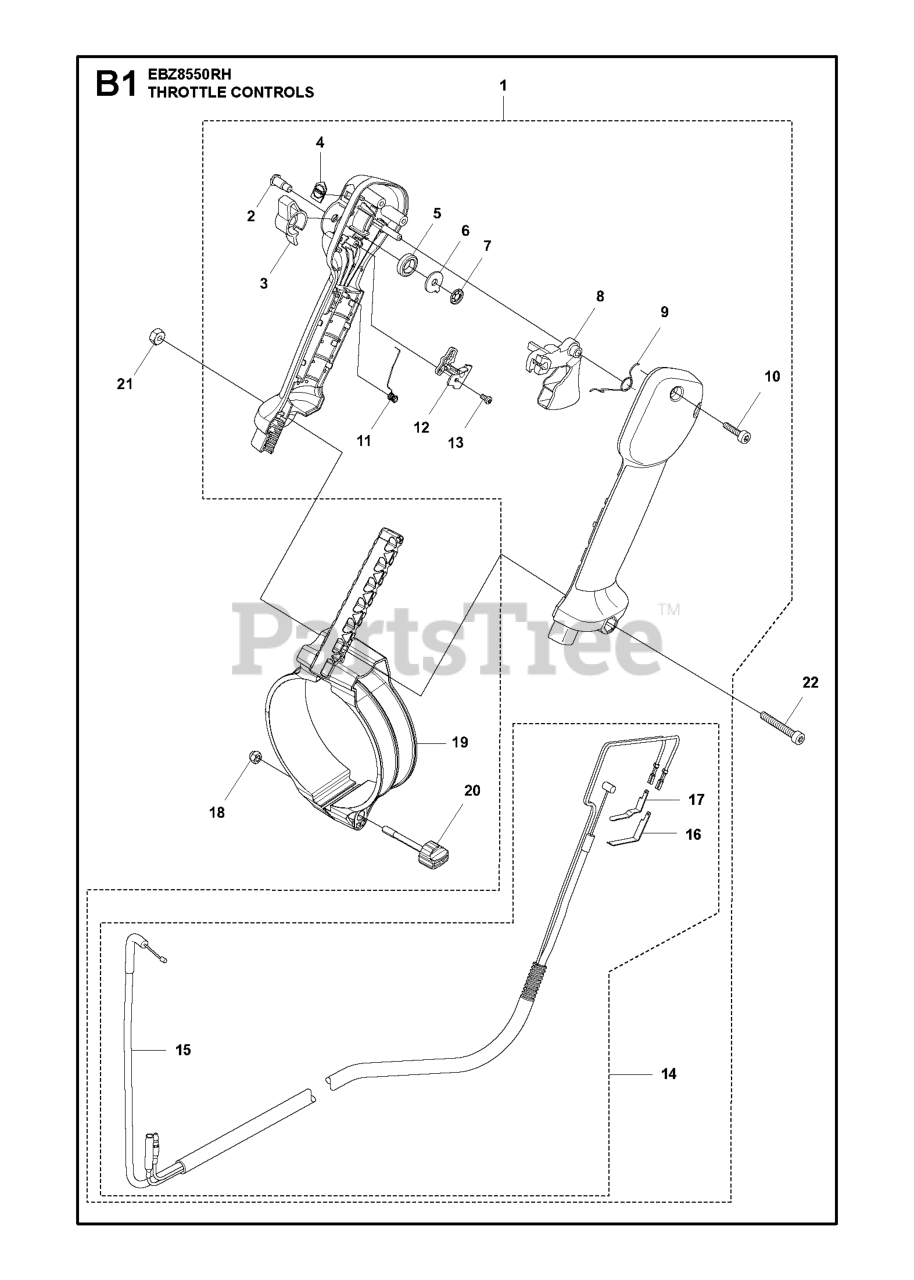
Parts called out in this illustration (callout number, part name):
1	THROTTLE LEVER ASSY, LEVER SUB
2	SHAFT PIVOT
10	SCREW
12	RETAINER
14	WIRING ASSY
15	CABLE, COMP
16	CONTACT SPRING
17	CONTACT SPRING
18	NUT
19	HANDLE HOLDER RIGHT THROTTLE
21	NUT
